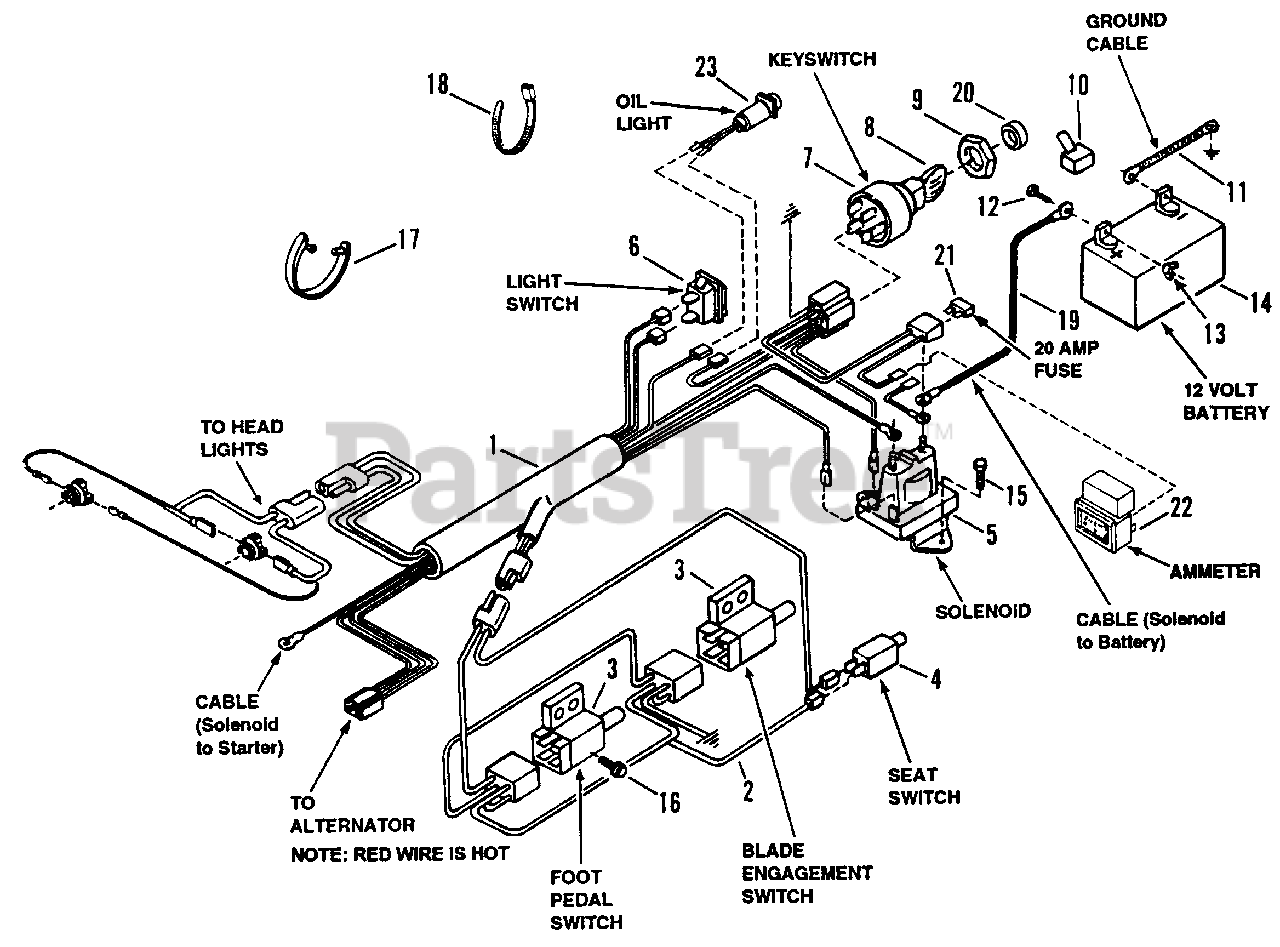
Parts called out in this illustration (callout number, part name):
1	HARNESS, Wiring (Kohler Engine)
2	HARNESS, Interlock
3	SWITCH, Clutch & PTO
4	SWITCH, Seat NC
5	SOLENOID
6	SWITCH, Light
7	SWITCH, Key
8	KEY, Switch (With Cover)
9	NUT, 5/8-32 Hex
10	COVER, Positive Terminal
11	CABLE, Negative 15" 8 AWG Black
12	BOLT, 1/4-20 x 3/4" Carriage
13	WING-NUT, 1/4-20
14	KIT, Battery
15	SCREW, 1/4-20 x 1/2" Self-Tapping
16	SCREW, #10-24 x 1/2" Hex Washer Self-Tap (Torx)
17	TIE, Wire
18	TIE, Cable 7"
19	CABLE, Positive 11" 8 AWG Red
20	BEZEL
21	FUSE, 20 Amp
22	AMMETER
23	OIL LIGHT
